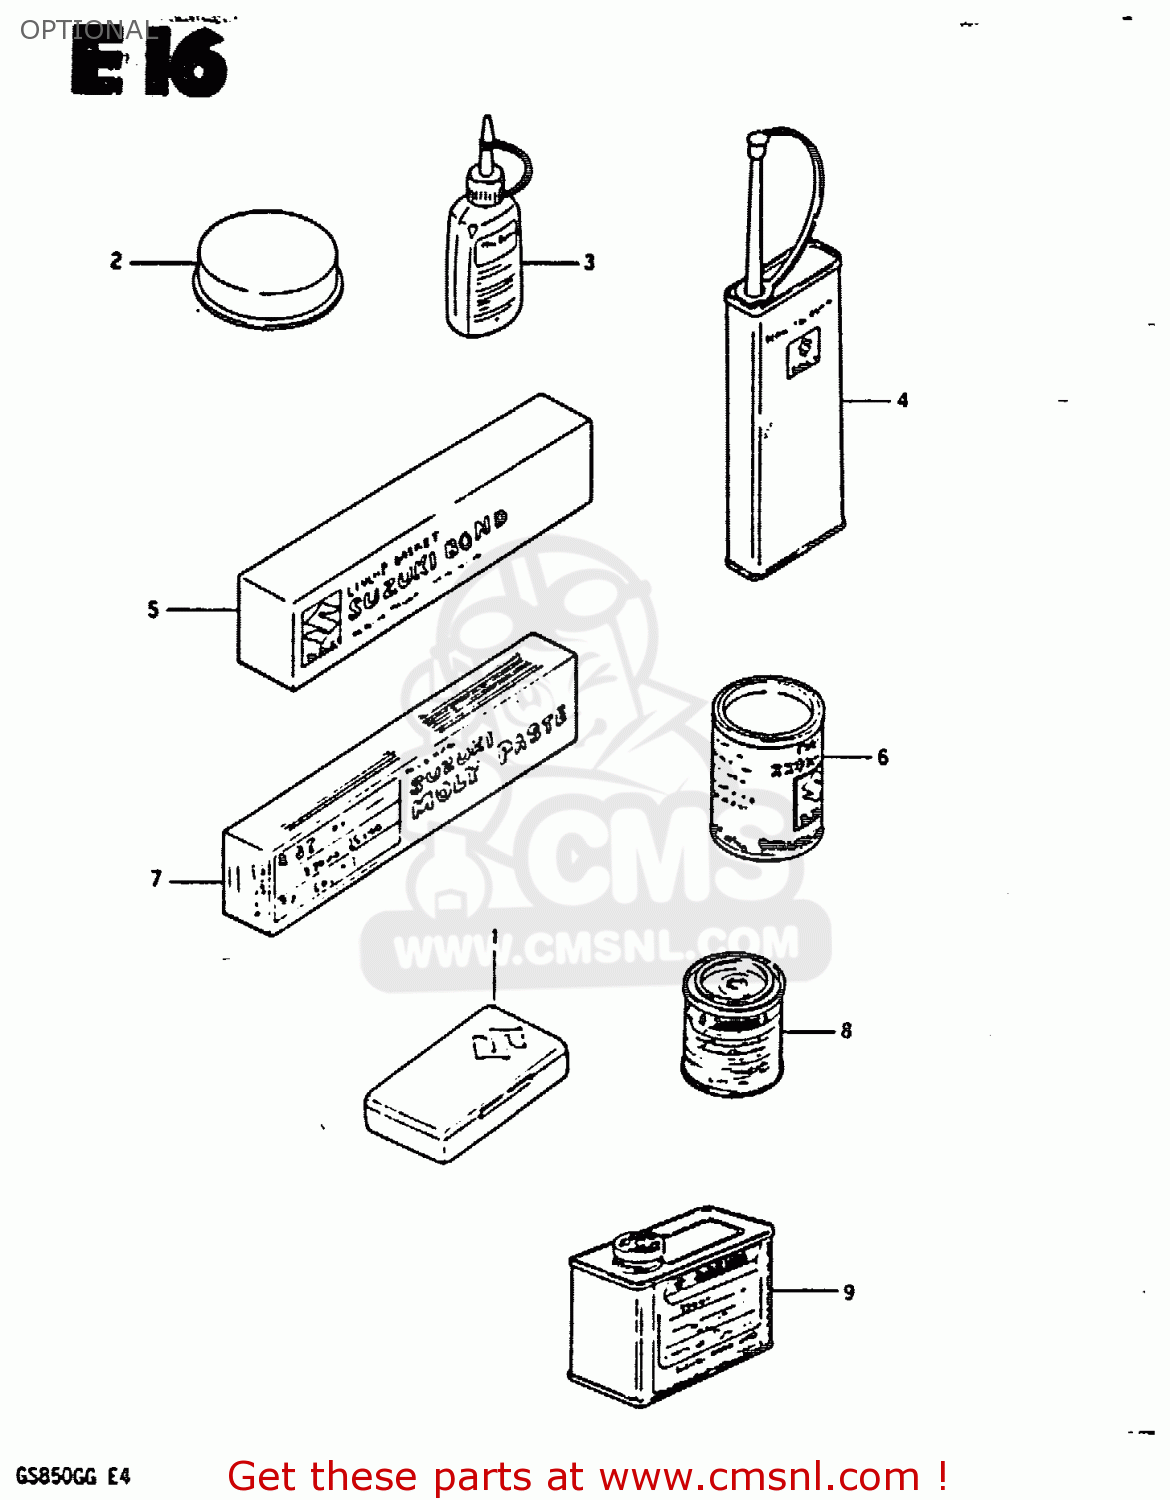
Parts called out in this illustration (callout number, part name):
1	TUBE REPARING TOOL
2	GREASE,PBC FOR BRK PAD 20G
3	THREAD LOCK NO.1342
4	THREAD LOCK NO.1401 CLEAR 200G
5	LIQUID GSKT NO.1207B 100G BLK
6	GREASE(C)EP2 LITHIUM 150G
7	SUZUKI MOLY PASTE
8	PAINT,BLACK
9	PAINT (BLACK)
